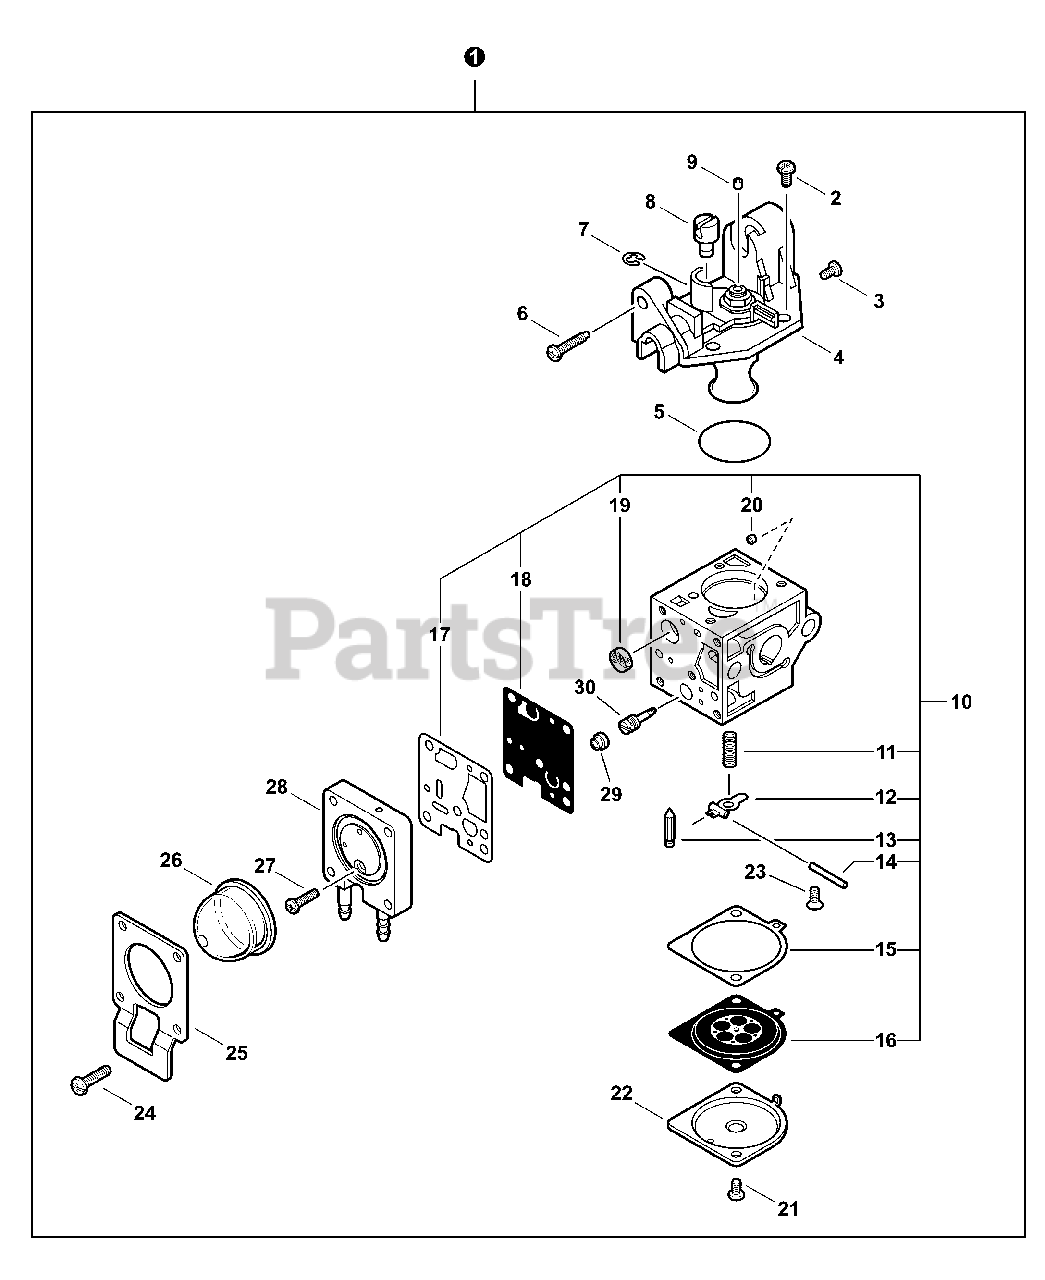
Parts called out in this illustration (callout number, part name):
1	CARBURETOR -- RB-K91A
4	ROTOR COVER ASSY
6	SCREW, IDLE ADJUST
7	RING, RETAINING
10	REPAIR KIT
11	SPRING, METERING LEVER
12	LEVER, METERING
13	VALVE, INLET NEEDLE
14	PIN, METERING LEVER
15	GASKET, DIAPHRAGM
16	DIAPHRAGM, METERING
17	GASKET, PUMP
18	DIAPHRAGM, PUMP
19	STRAINER
20	GUIDE, ROLLER
22	COVER, METERING
23	SCREW, METERING LEVER PIN
24	SCREW, PURGE BULB RETAINER
25	RETAINER, PURGE BULB
26	BULB, PURGE
27	SCREW, PURGE BASE
28	BASE, PURGE
30	NEEDLE - HIGH SPEED
